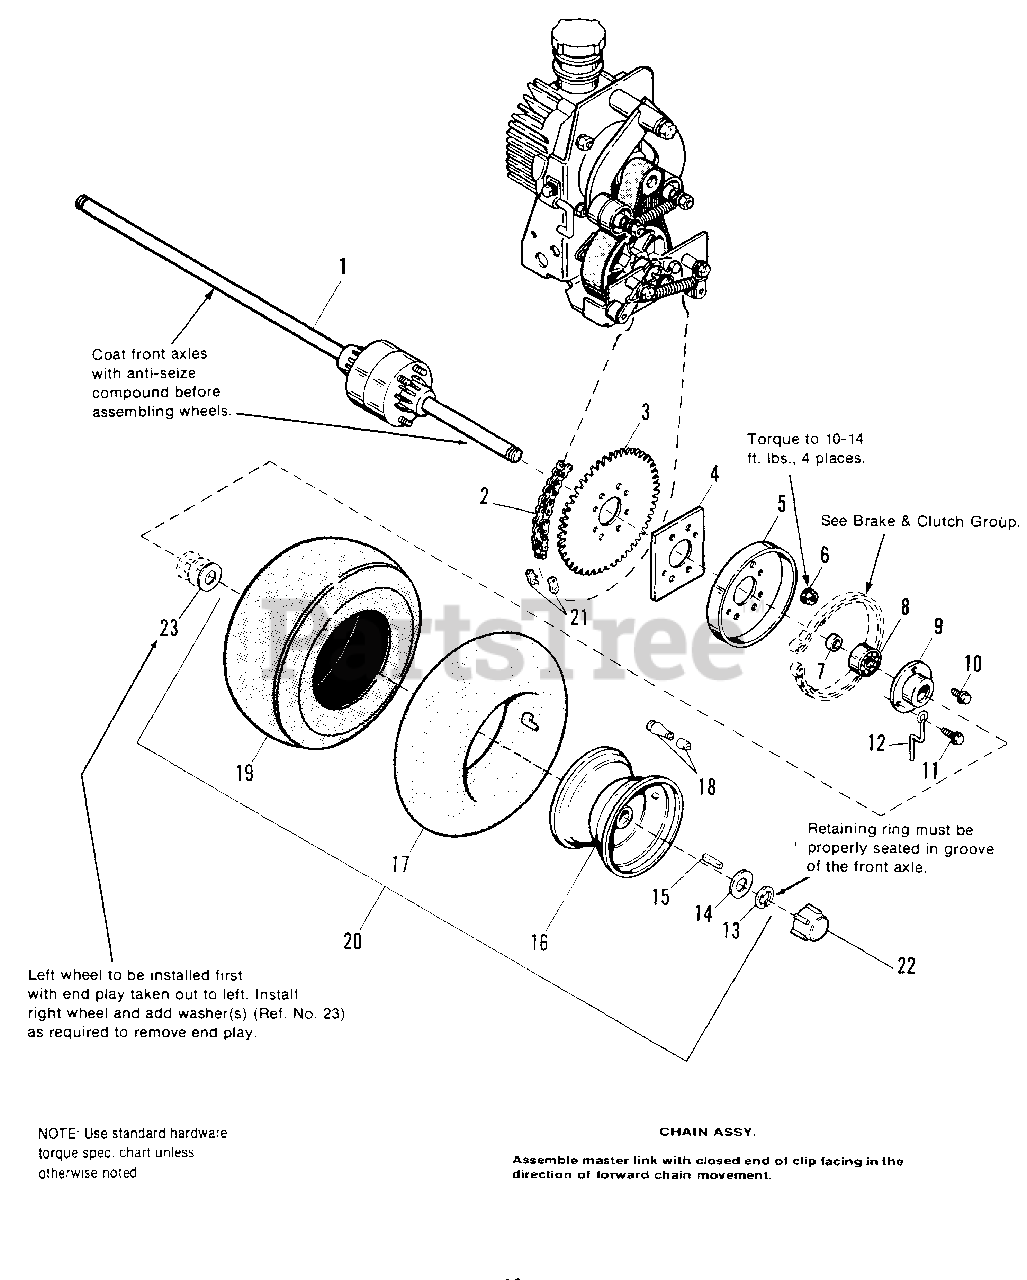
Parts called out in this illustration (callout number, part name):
1	AXLE ASSY., Differential
2	CHAIN, Roller, #40 x 63 pitches
3	SPROCKET, 54 Tooth
4	SHIM, Sprocket
5	DRUM, Brake
6	NUT, Flange Lock, 5/16-18
7	SPACER, Axle
9	FLANGE, Bearing
10	SCREW, Taptite, 5/16-18 x 1/2
11	SCREW, Taptite, 5/16-18 x 3/4
12	STOP, Brake Band
13	RING, Retaining, Wheel
14	WASHER, 3/4
15	KEY, 3/16 x 3/16 x 1-1/2
16	WHEEL ASSY.
17	TUBE (Service Only) (See note below.)
18	VALVE STEM & CAP
19	TIRE, 15 x 6.00-6
20	WHEEL & TIRE ASSY., 15 x 6.00-6
21	MASTER LINK, Chain #40
22	CAP, Threaded
23	WASHER, Shim, 3/4 x 1-1/6(Use as needed.)
